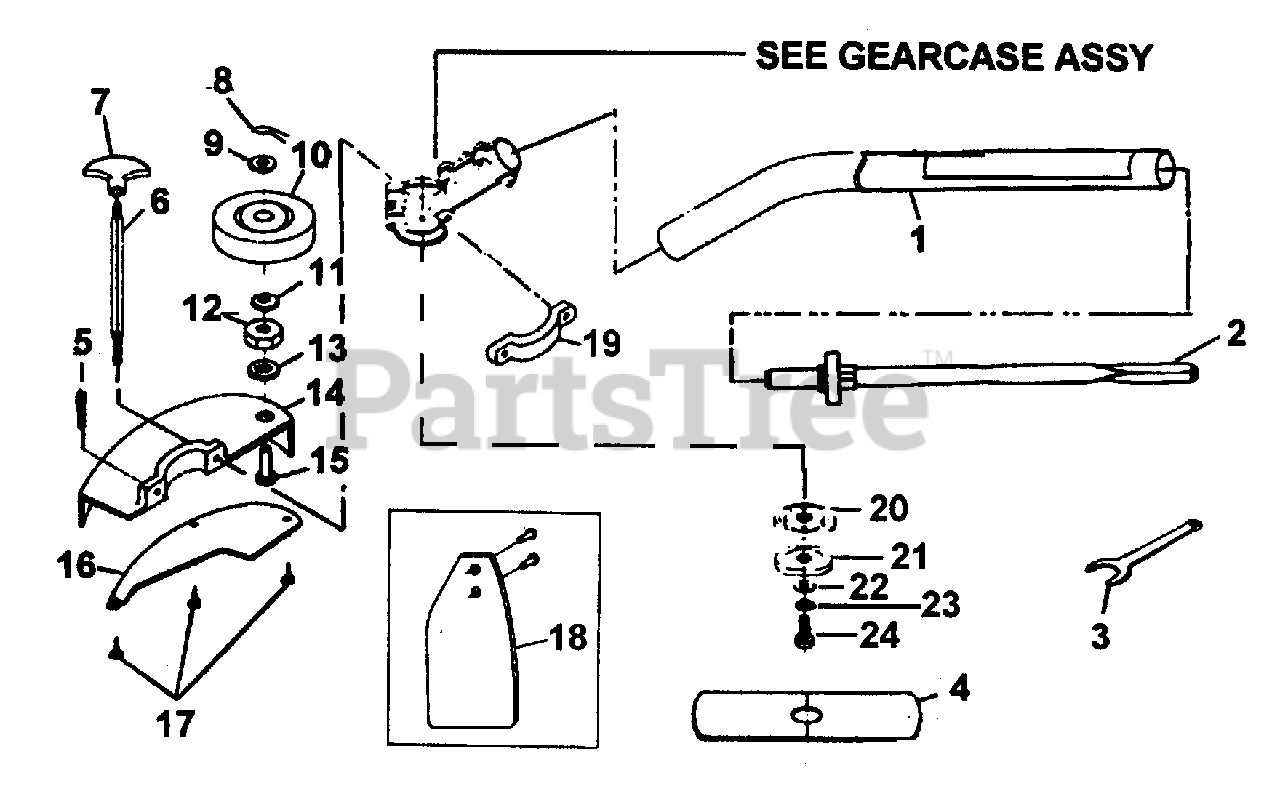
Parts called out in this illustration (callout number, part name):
1	TUBE ASSY
2	FLEX CABLE
3	SPANNER WRENCH
4	EDGER BLADE
5	SCREW, ALLEN HEAD
6	SHAFT AND KNOB
8	COTTER PIN
9	WASHER, FLAT
11	WASHER, FLAT
12	NUT
13	WASHER, FLAT
14	GUARD, EDGER
15	EDGER AXLE
16	SHIELD, EDGER
17	SCREW, SELF TAPPING
18	DRAG FLAP KIT
21	HOLDER B
22	WASHER, FLAT
23	WASHER, LOCK
24	BOLT, L.H. THREAD
